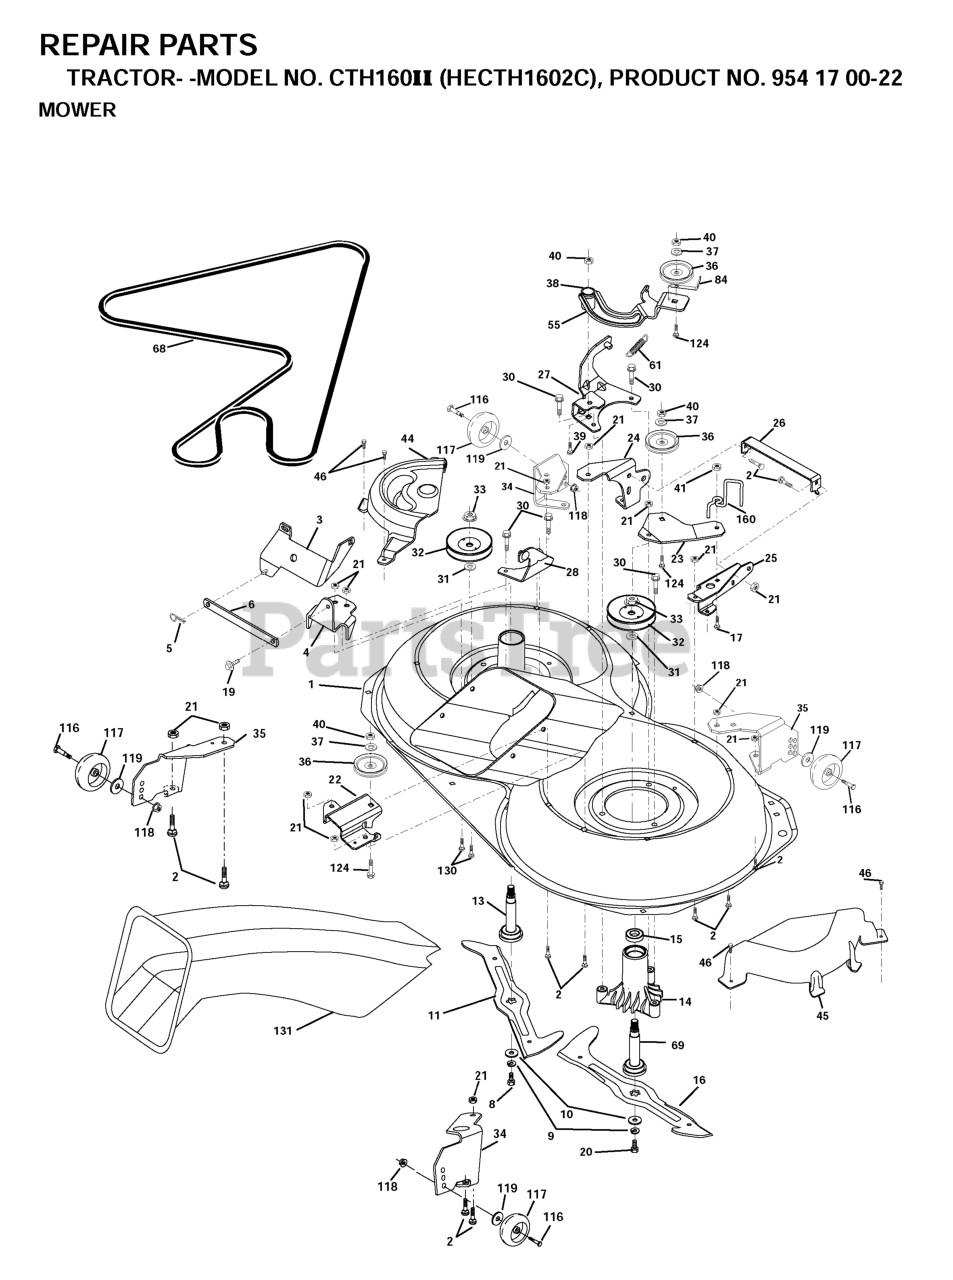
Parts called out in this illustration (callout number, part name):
1	Housing Asm. Mower 107 CRD
2	RP BOLT 5/16-18 X3/4 ZN/YEL GR
5	RETAINER-SPRNG RB
6	BAR.SWAY.92.CRD
8	BLADE BOLT
9	LOCKWASHER
10	WASHER.BLADE
11	BLADE, LH (CTH150)
13	SHAFT ASM VENT
14	HOUSING.MANDREL.VENTED (MACHD)
16	RP BLADE RH (CTH150)
17	BOLT.3/8-14X1.25
19	BOLT SHD 5/16-18
21	LOCKNUT
22	BRACKET.IDLER.RR.107.CRD
25	BRACKET.SUSPENSION.RF.107.CRD
26	BRACE.SUPT.SUSP.FRT.CRD
28	BRACKET
30	SCREW THDROL ROLLING WASHER HD
31	WASHER
33	NUT
34	BRACKET
36	PULLEY.IDLER.4.25
37	WASHER
41	NUT LOCK FLG 3/8-16 UNC
44	Cover Mandrel Lh 107 CRD
45	MANDREL COVER RH
46	SCREW.1/4-20X5/8
55	ARM.IDLER.107.CRD
68	HEX-BELT 107 MOWER
69	SHAFT.ASM.W/LWR.BRG.RH.THREAD
84	KEEPER, BELT IDLER
116	BOLT, SHOULDER
117	WHEEL GAGE DONUT
118	LOCKNUT
119	WASHER.5/16.FLAT.STE.STD.
124	BOLT.3/8-16X1.50
130	BOLT.CARR.SQNK.5/16-18UNC.X3/4
131	CHUTE BAGGER
